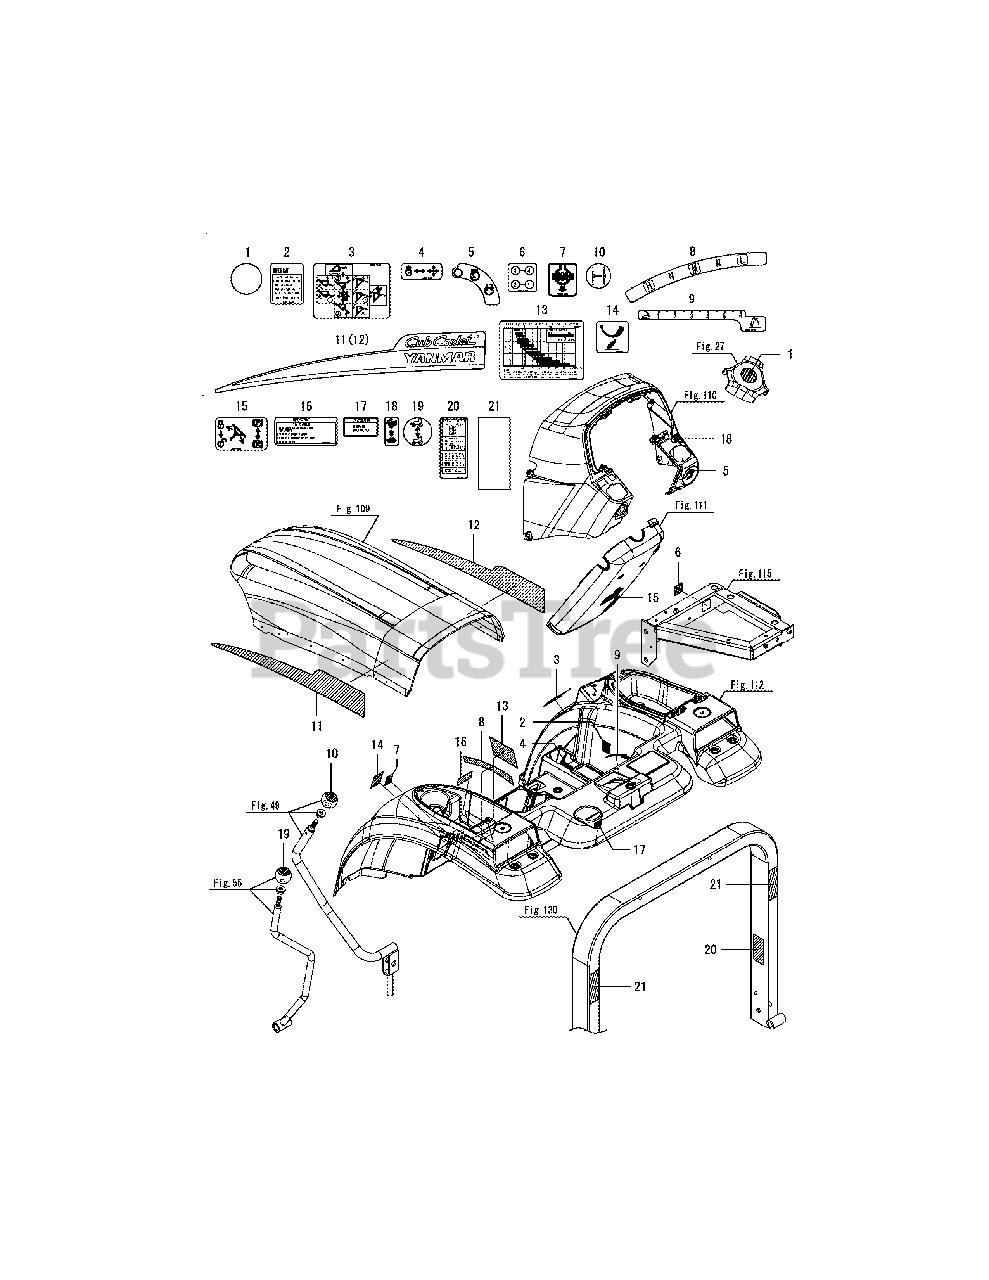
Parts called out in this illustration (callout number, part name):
1	LABEL, STEERING
2	LABEL,IMPORTANT,DIFF
3	LABEL, SCV LEVER
4	LABEL, SCV LOCK
5	LABEL, START SWITCH
6	LABEL, SCV COUPLER
7	LABEL, DIFF. LOCK
9	LABEL, LIFT LEVER
10	LABEL, PRIMARY SHIFT
11	LABEL, LOGO L.
14	LABEL, STOP VALVE
15	LABEL, TILT-PARKING
17	LABEL, FUEL OIL
18	LABEL,ACCELERATOR
20	LABEL,ROPS STANDARD
21	TAPE,REFLECTION
